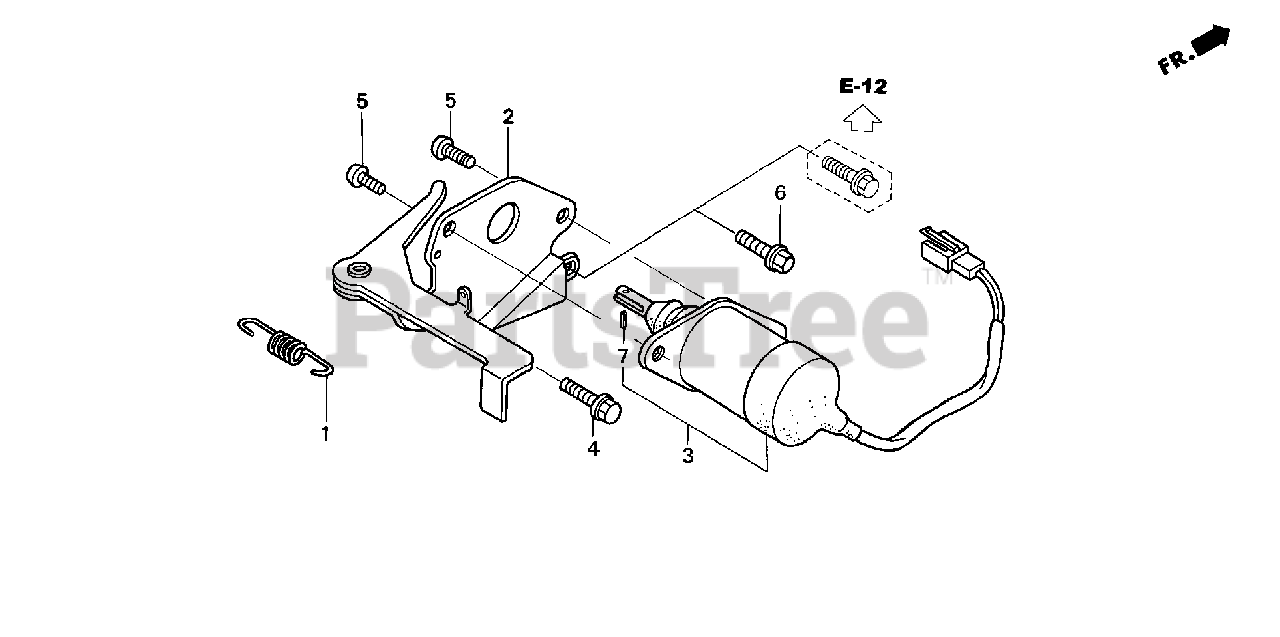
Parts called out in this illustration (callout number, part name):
1	SPRING, CHOKE RETURN
2	LEVER, THROTTLE
3	SOLENOID ASSY.
4	BOLT, FLANGE (6X12) (CT200)
5	SCREW, PAN (5X8)
6	BOLT, FLANGE (6X12) (CT200)
7	PIN, SPRING (2X6)
